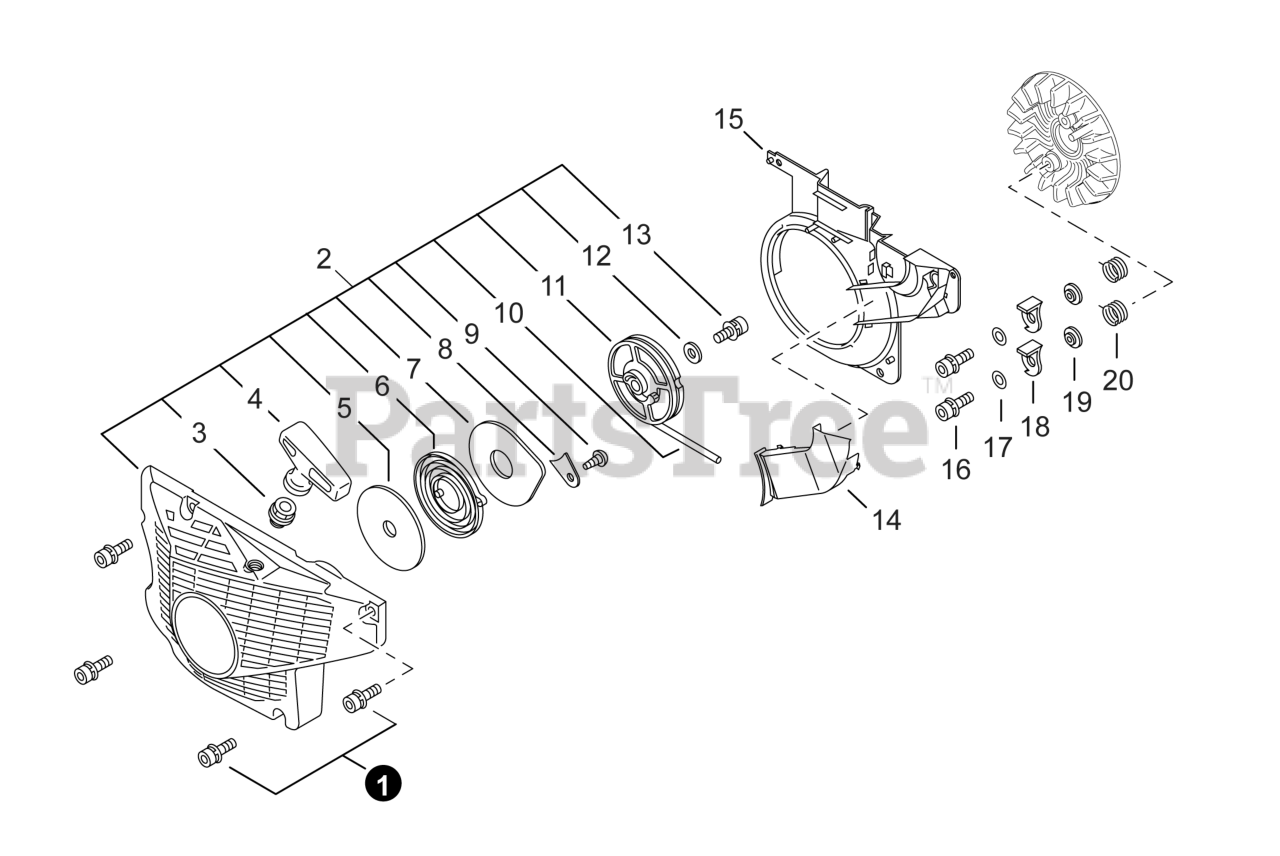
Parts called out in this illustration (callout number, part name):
1	BOLT 5×20
2	STARTER ASSY
3	GUIDE, ROPE
4	GRIP, STARTER
5	PLATE, STARTER
6	SPRING, RECOIL
7	PLATE, STARTER
8	PLATE, EYE
9	SCREW 4×8
10	ROPE, STARTER 4.0×950
11	REEL, ROPE
12	WASHER 5.5×12×0.8
13	BOLT 5×14
14	DUCT, AIR
15	COVER, FAN
16	BOLT 5×18
17	WASHER 5.5×12×0.8
18	PAWL, STARTER
19	COLLAR 5
20	SPRING, RETURN
